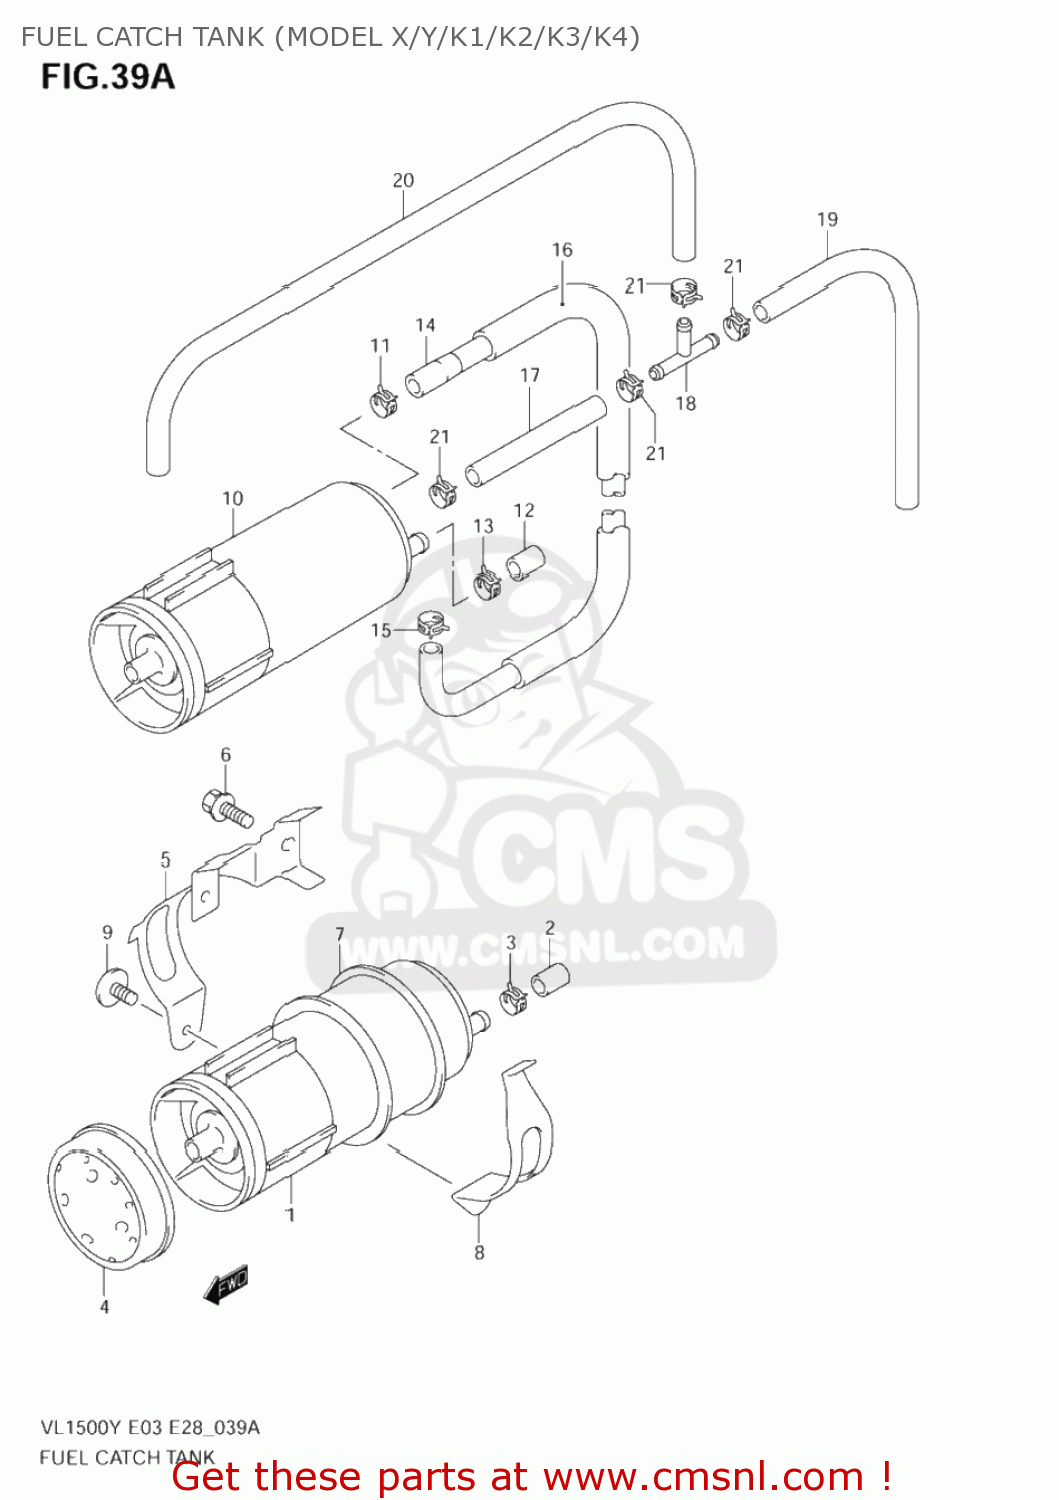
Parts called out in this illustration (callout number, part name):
1	TANK,FUEL CATCH
2	CAP,OD:11.5
3	CLIP
4	CAP,CANISTER
5	BRACKET,CATCH TANK
6	BOLT(6X16)
7	CUSHION,CANISTER
8	HOLDER,CATCH TANK
9	SCREW 6X12
10	CANISTER ASSY,CHARCOAL
11	CLIP
12	CAP,OD:11.5
13	CLIP
14	HOSE,CANISTER & CARB PURGE
15	CLIP
16	PROTECTOR(14.5X15.5X600)
17	HOSE(5.4X11.4X600)
18	JOINT,3 WAY
19	HOSE(5.4X11.4X600)
20	HOSE(5.4X11.4X600)
21	CLIP
